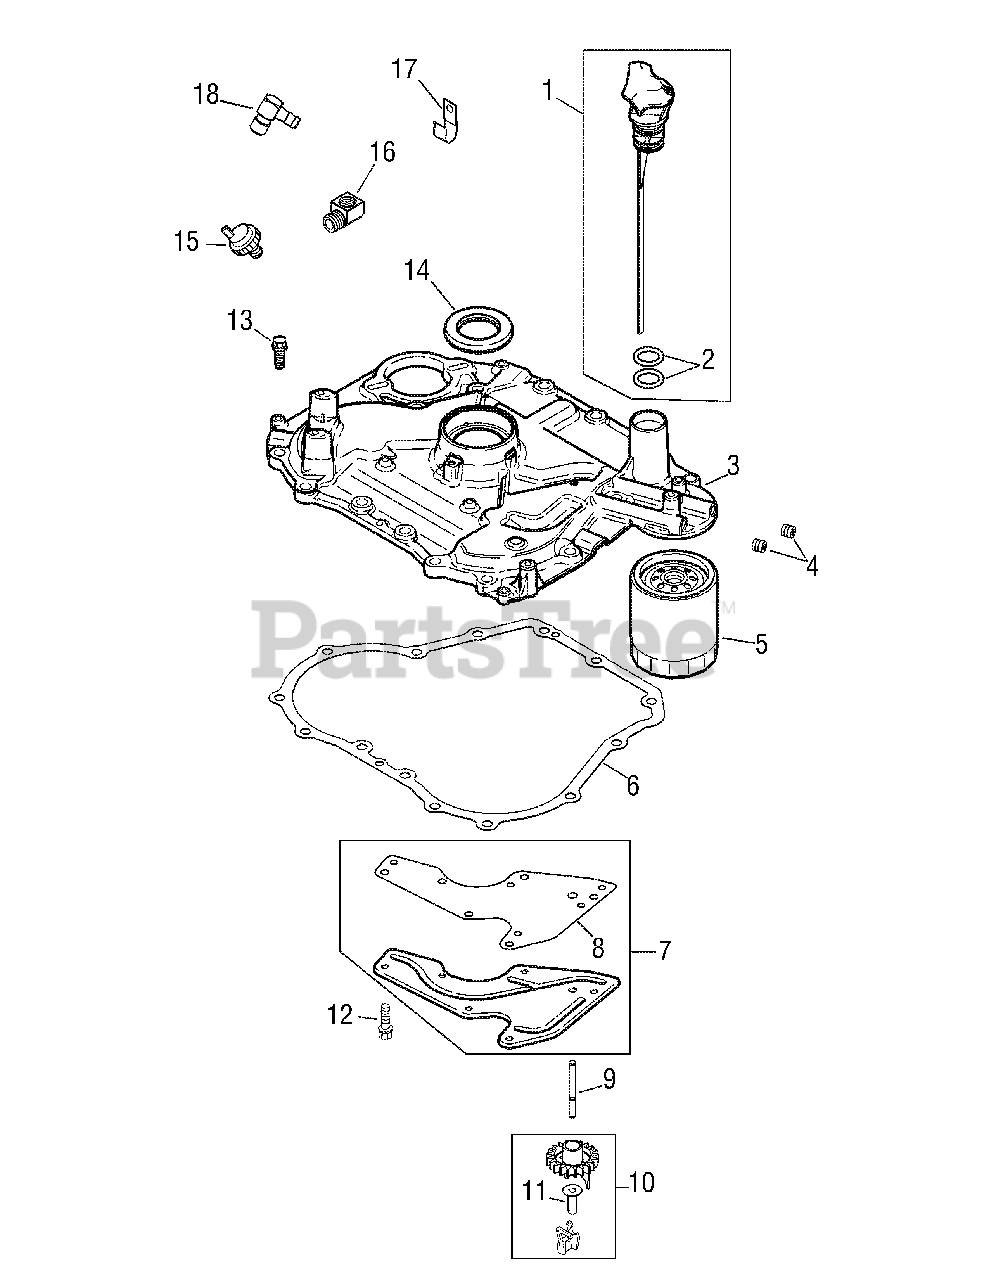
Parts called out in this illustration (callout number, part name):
1	Kit, dipstick assembly
2	O-Ring, dipstick
3	Plate assembly, closure
6	Gasket, closure plate
7	Kit, oil passage cover
8	Gasket, oil passage
9	Shaft, governor gear
10	Kit, gear and weight assembly
11	Pin, governor regulating
12	Screw, hex. flange M5x0.8x13
13	Screw, hex. flange M8x1.25x30
14	Seal, oil
15	Switch, pressure
16	Elbow, street
17	Clip, cable
18	Connector, 90
